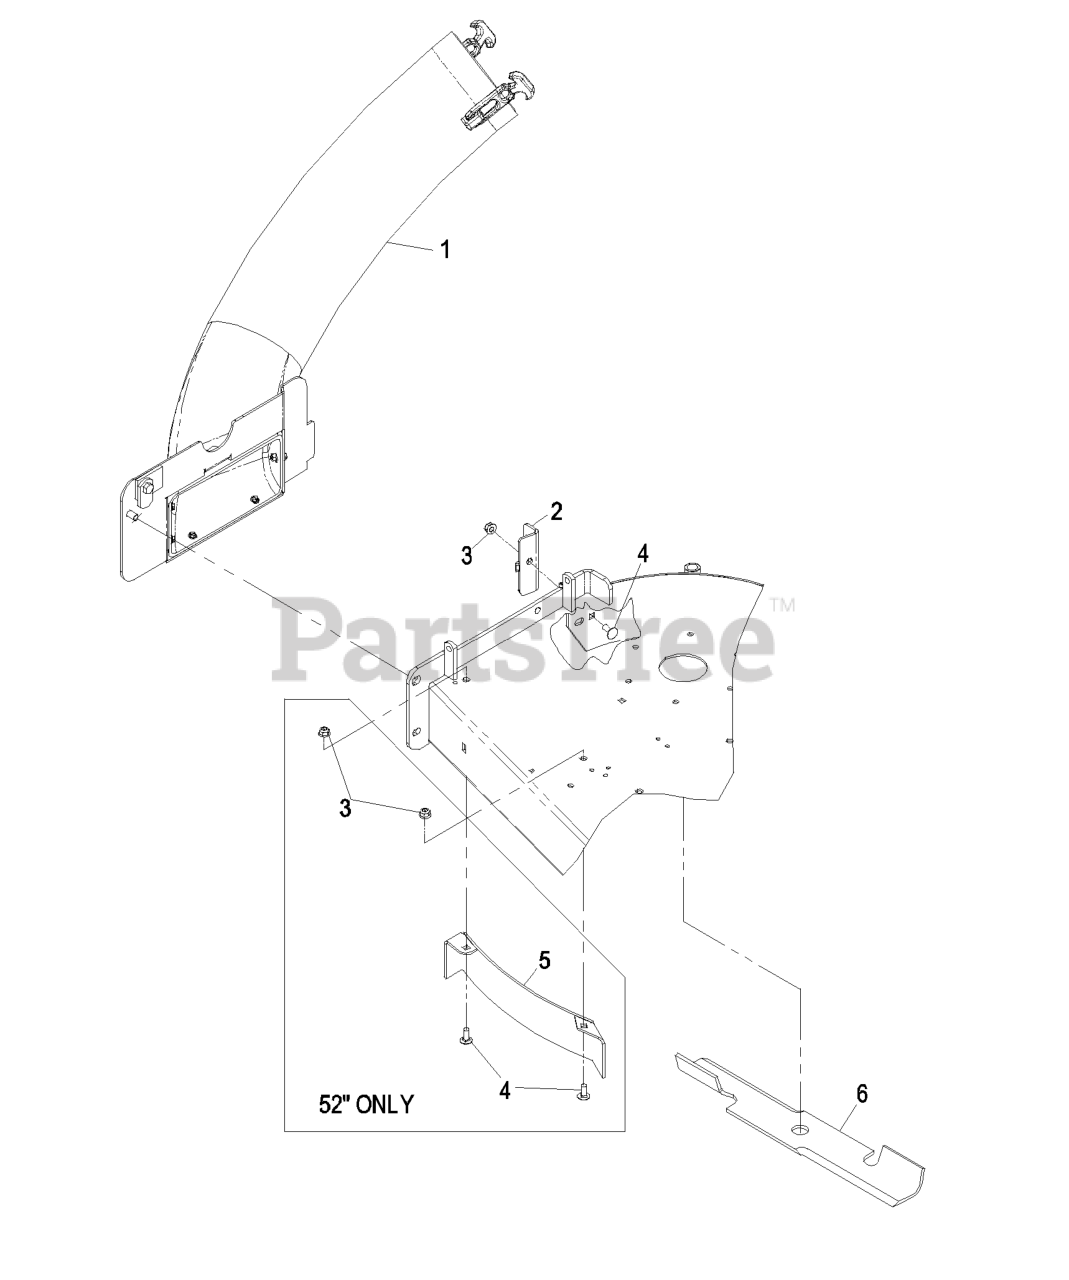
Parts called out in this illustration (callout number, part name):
1	TUBE AND STRAP ASM
2	BRACKET-BOOT MOUNT, 52 IN
3	NUT-HF, NI
4	SCREW-CARR
5	BAFFLE-DISCHARGE, 52 INCH
